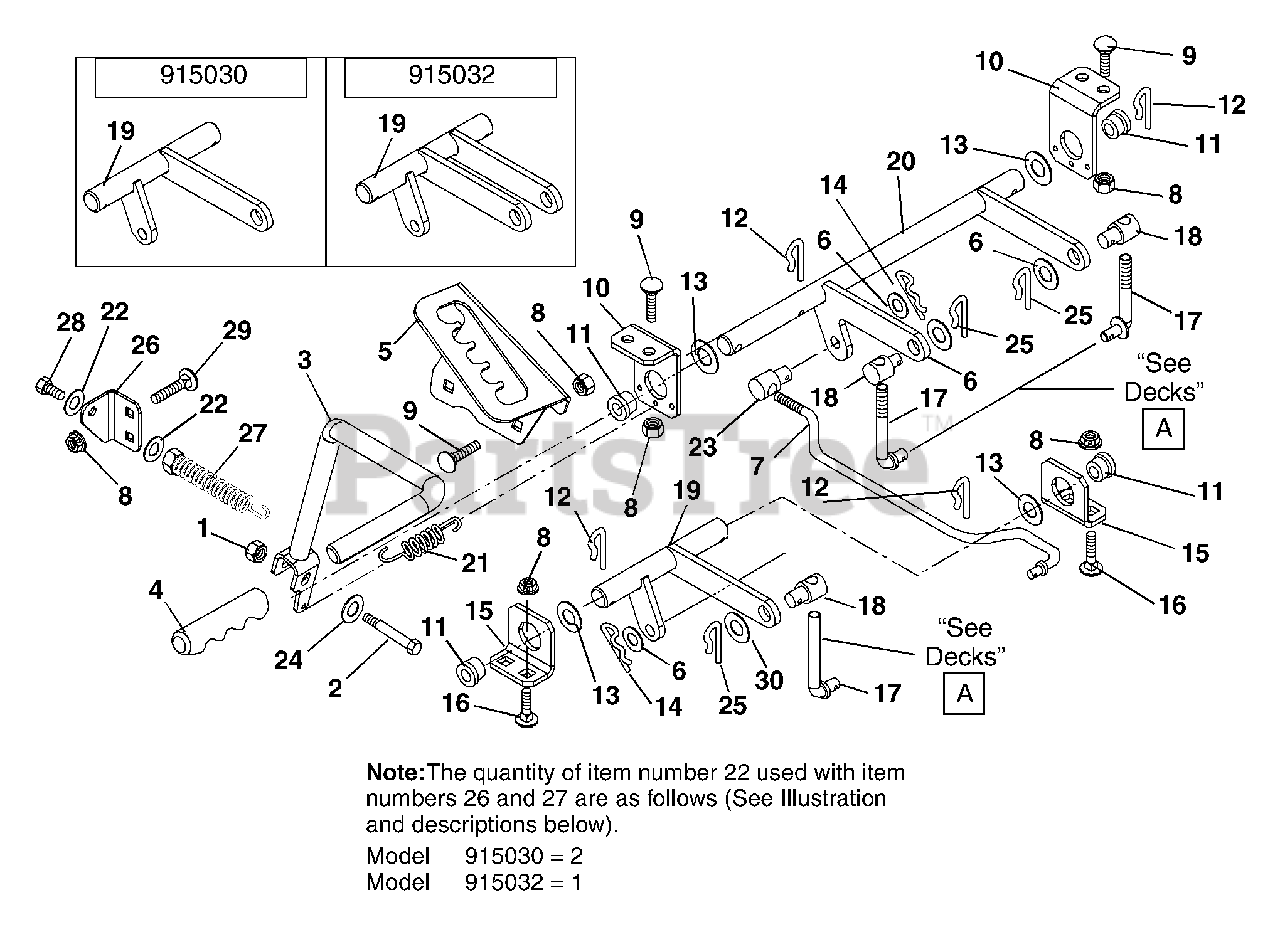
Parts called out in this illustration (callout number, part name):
1	Nut, Locking Top Flange .31-18
2	Bolt, 1.25 Socket Shoulder Plain
3	Weldment, Lift Handle
5	Detent Plate
6	Washer, Flat Steel .511 x 1.44 x .125
7	Rod, Deck Lift
8	Nut, Locking Top Flange .38-16
9	Bolt, Round Head Square Neck .38-16 x .75 Grade 5
10	Bracket, Lift
11	Bushing, Flange .75 x 1.00 x .625 x 1.25
12	Pin, Spring Clip
13	Washer-Flat-Steel .812 x 1.50 x .135
14	Pin, Hair #16
15	Bracket, Deck Pivot
16	Bolt, Round Head Square Neck .38-16 x 1.00 Grade 5
17	Rod, Link (030)
17	Rod, Link (032)
18	Trunnion (030)
18	Trunnion (032)
19	Weldment, Front Lift (030)
19	Weldment, Front Lift (032)
20	Weldment, Lift
21	Spring, Extension
22	Washer, Flat Steel .43 x 1.00 x .16 (030)
22	Washer, Flat Steel .43 x 1.00 x .16 (032)
23	Pivot, Rod
24	Washer, Flat Steel .43 x 1.00 x .160
25	Clip, Spring
26	Bracket, Spring Anchor
27	Spring, Tension .195 x 1.15 x 5.50
28	Bolt-Hex .38-16 x 1.50 Grade 5
29	Bolt-Round Head Square Neck .38-16 x 1.25
30	Washer, Flat Steel .563 x 1.38 x .109
